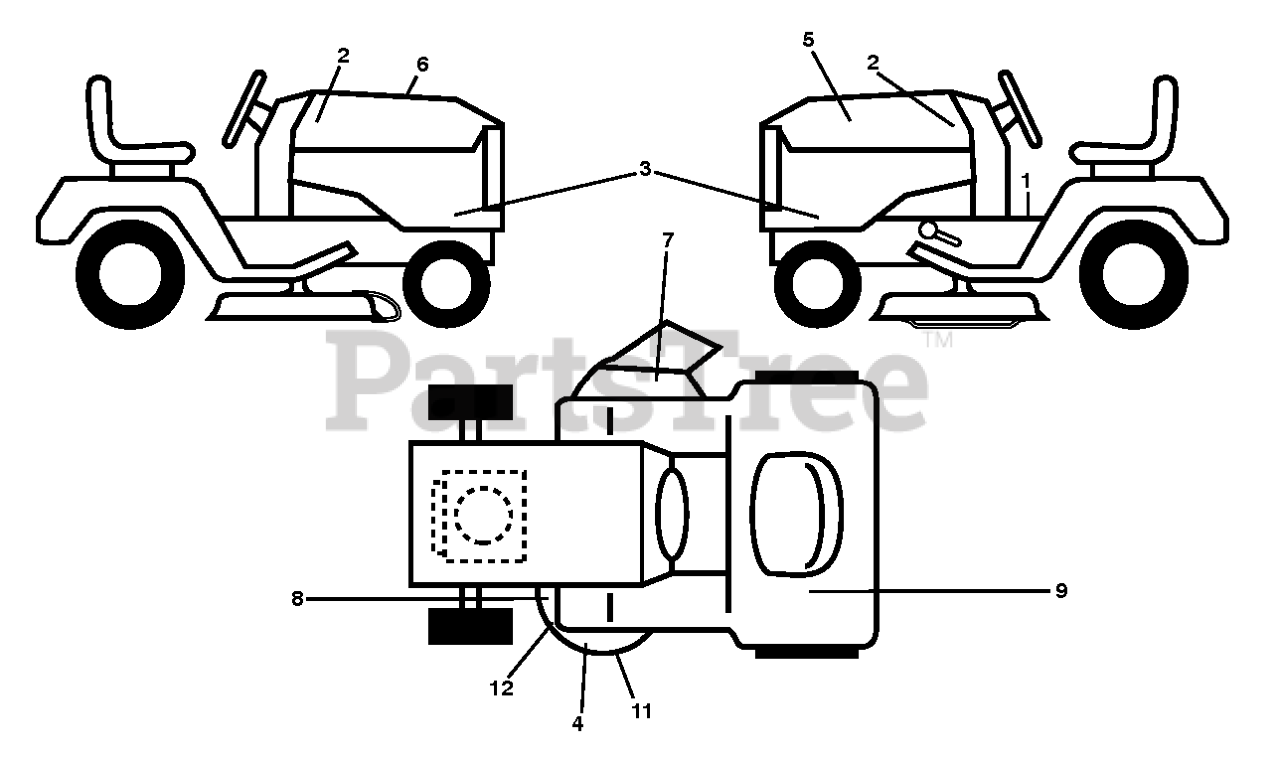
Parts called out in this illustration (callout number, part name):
1	DECAL.WARN.STARTINST.LOWEARIEN
2	DECAL.BADGE.170MM.TEXTLOGO.
3	DECAL.SDPNL.HUSQGT.YT42DXL.SET
4	DECAL.DECK.CLEARCUT.NOSTEP
5	DECAL.WARNING.CUST.RESP.E85.
6	DECAL.RPL.KOH.KT7.TLB.42F.K46
7	DECAL.TRACT/ZTR.DECKWARN.HUSQ
8	DECAL DECK DECAL DECAL.DECK.WA
11	DECAL DECK DECAL DECAL.42DECK.
12	DECAL.V-BELT.SCH.42/46"MEC/ELE
